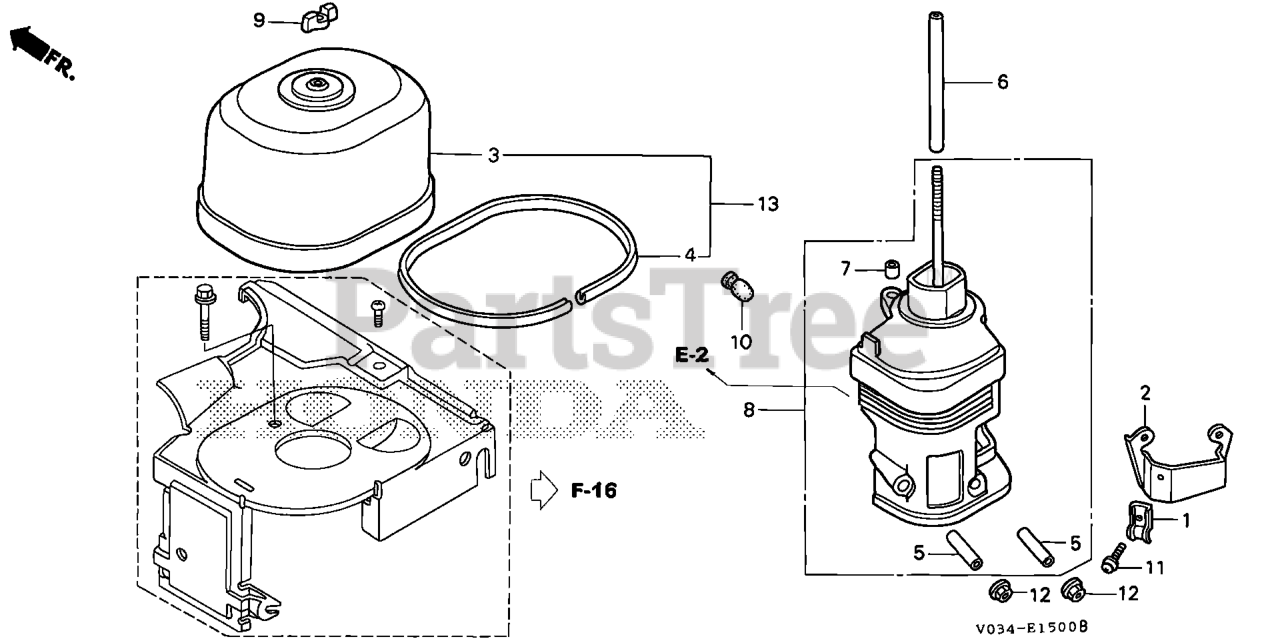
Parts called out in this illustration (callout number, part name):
1	HOLDER, CONTROL CABLE Use from Engine SN 2327377.
2	STAY, WIRE HOLDER
3	COVER, AIR CLEANER (STD)
4	RUBBER, AIR CLEANER COVER
5	COLLAR, AIR CLEANER
6	COLLAR, AIR CLEANER
7	COLLAR B, AIR CLEANER
8	ELBOW, AIR CLEANER
9	WINGNUT, TOOL BOX SETTING
10	PLUG, CONE TYPE
11	SCREW-WASHER (5X16)
12	NUT, FLANGE (6MM)
13	COVER, AIR CLEANER
